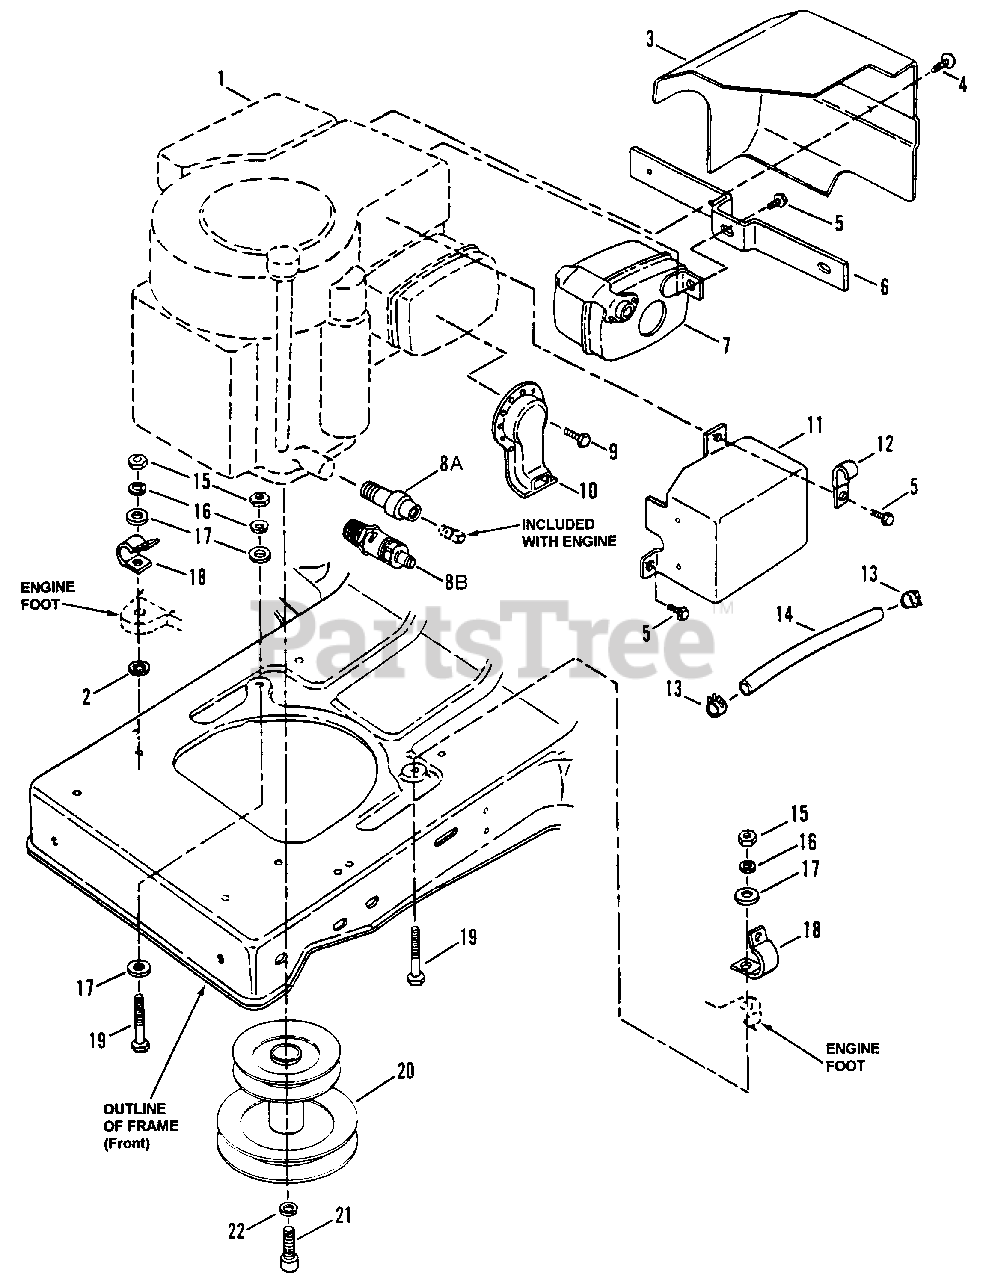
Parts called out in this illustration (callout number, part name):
2	WASHER, 5/16 Internal Tooth Lock
3	HEAT SHIELD
4	SCREW, #10-24 x 1/2" Hex Washer Self-Tap (Torx)
5	BOLT, 1/4-20 x 1/2" Hex Flange Lock
6	BRACKET, Heat Shield
7	MUFFLER, Exhaust
8A	EXTENSION, Oil Drain
8B	EXTENSION, Oil Drain
9	SCREW, #8-18 x 1/2 Hex Head, Self-Tapping
10	EXTENSION, Muffler
11	HEAT SHIELD, Muffler
12	CLIP, "J" Type
13	CLAMP, Fuel Line
14	LINE, Fuel, 16" Long
14	LINE, Fuel, 7" Long
15	NUT, 5/16-18 Hex
16	WASHER, 5/16 Split Lock
17	WASHER, 5/16 Flat
18	CLIP, Wiring Harness
19	SCREW, 5/16-18 x 1 3/4 Hex Head Cap
20	ASSEMBLY, Engine Pulley
21	SCREW, 7/16-20 x 1" Hex Cap, Socket Head
22	WASHER, 7/16 Split Lock
